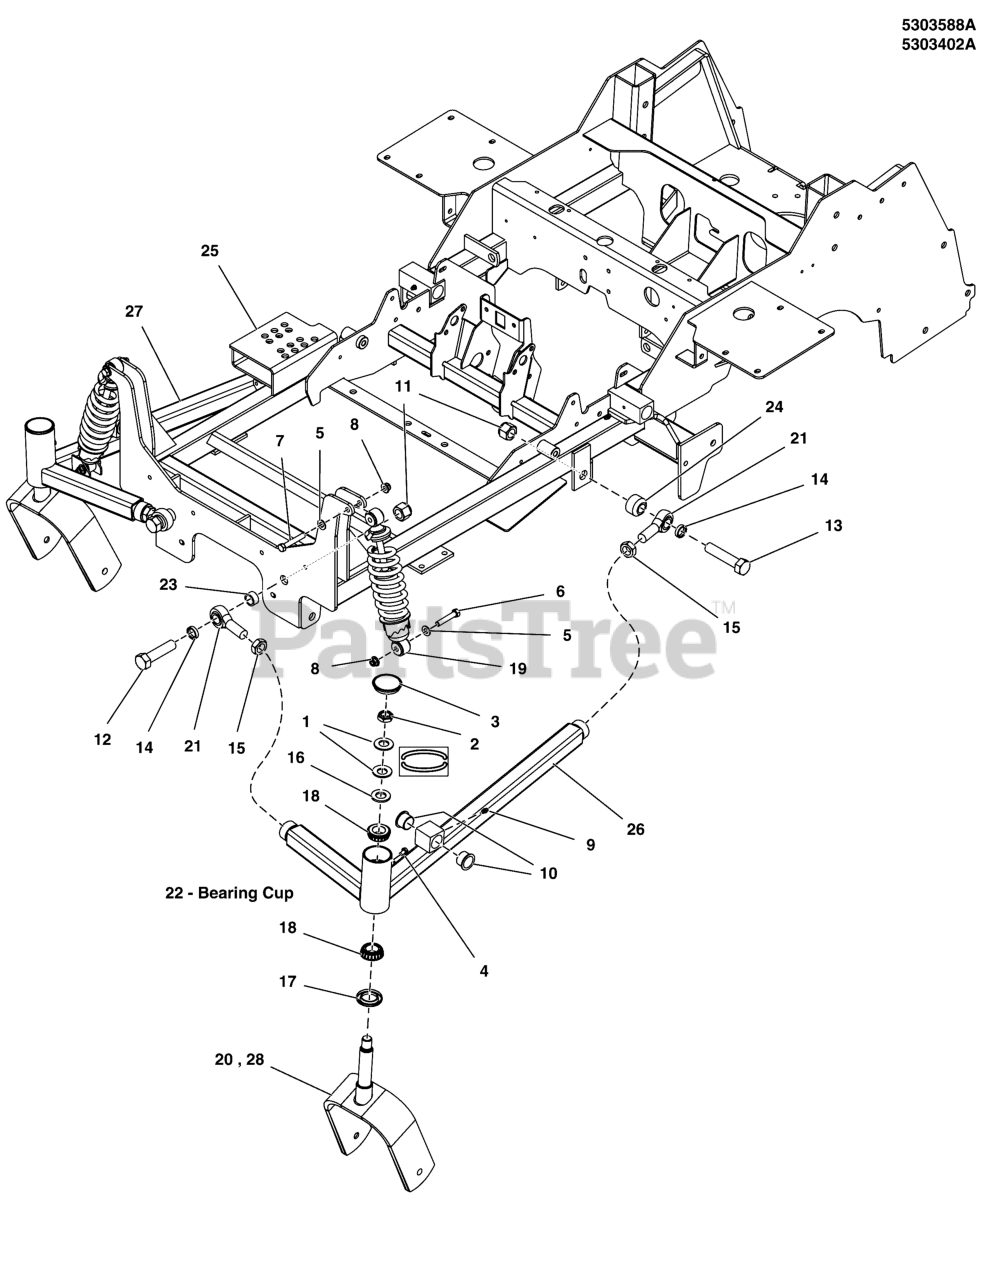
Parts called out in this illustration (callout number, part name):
1	WASHER, BELLEVILLE - 1.500 X .755
2	NUT, 3/4-16, HEX JAM NYLON LOCK
3	CAP, GREASE, LOW PROFILE
4	BOLT, 1/4-28 X 1/2, GD5 YZ
5	WASHER, 3/8 SAE
6	BOLT, 3/8-16 X 2, GD5, CZ
7	BOLT, 3/8-16 X 2-1/4" GD5 CZ
8	NUT, 3/8-16 HEX NYLOCK FLANGE
9	GREASE FITTING, 1/4-28 STRAIGHT
10	BUSHING, 1.00 X 1.13 X .75, PLASTIC
11	NUT, 3/4-16 HEX NYLON LOCK
12	BOLT-3/4-16 X 3 YZ GD8
13	BOLT, 3/4-16 X 3-1/2 YZ GD8
14	SPACER, .76 X 1.00 X .25
15	NUT, 3/4-16 HEX JAM
16	WASHER, 3/4 SAE
17	SEAL, GREASE
18	BEARING, TAPERED ROLLER, 1
19	SHOCK / SPRING ASSEMBLY, OE22375
20	WELD, CASTER YOKE - RED
21	BALL JOINT, 3/4-16, MALE
22	BEARING, CUP (SV)
23	SPACER, .76 X 1.00 X .50, CZ
24	SPACER, .75 X 1.50 X 1.00, CZ
25	* WELD, MAIN FRAME, IS2100Z - RED
26	WELD, FRONT A-ARM, LH - RED
27	WELD, FRONT A-ARM, RH - RED
28	WELD, CASTER YOKE - RED
